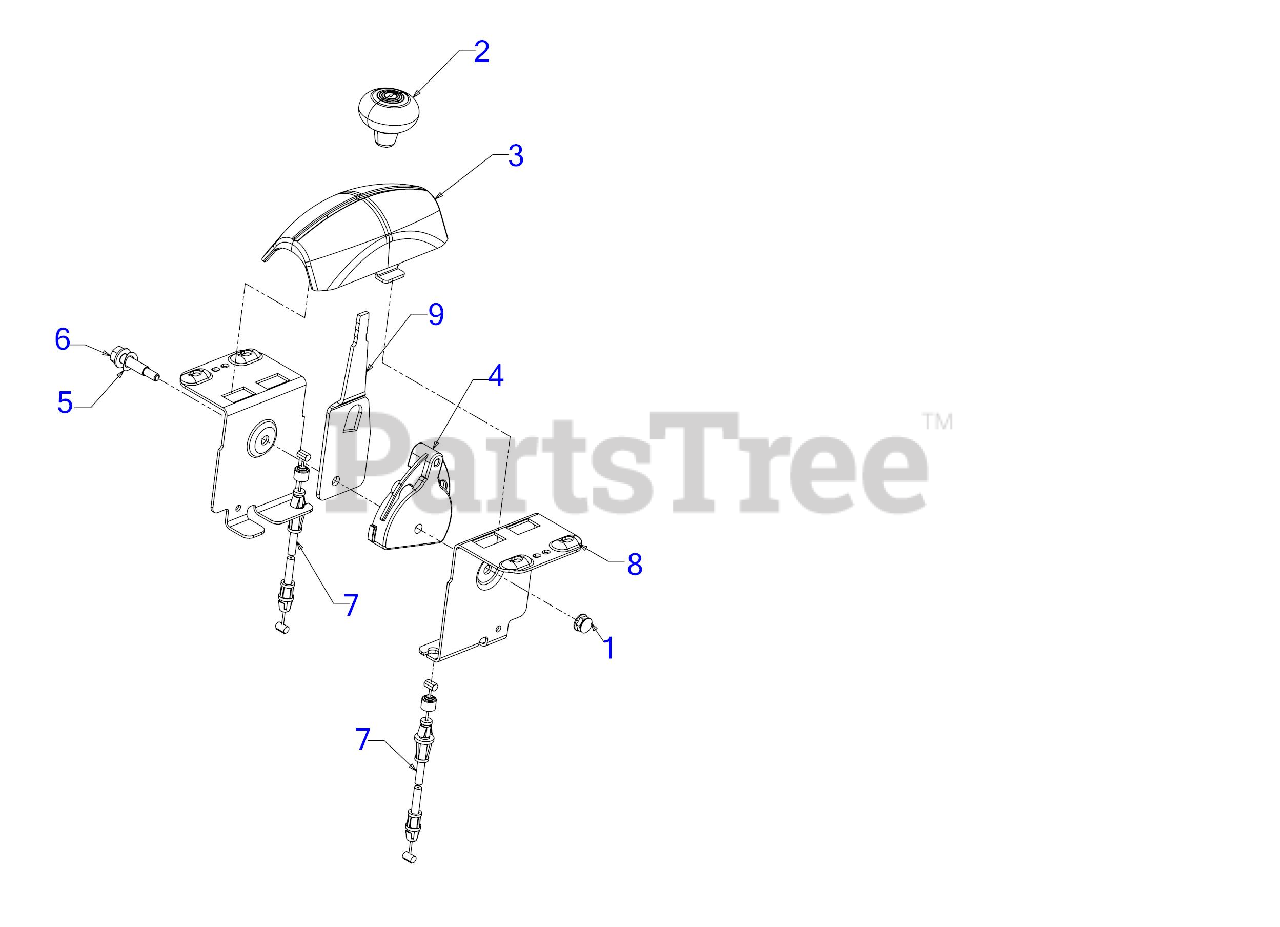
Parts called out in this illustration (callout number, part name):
1	FLANGE LOCK NUT
2	SHIFT KNOB
3	2 WAY CONTROL COVER
4	CABLE GUIDE
5	SPRING WASHER
6	SHOULDER SCREW
7	2 WAY CONTROL CABLE
8	2 WAY CONTROL BRACKET
9	2-WAY CONTROL LEVER
